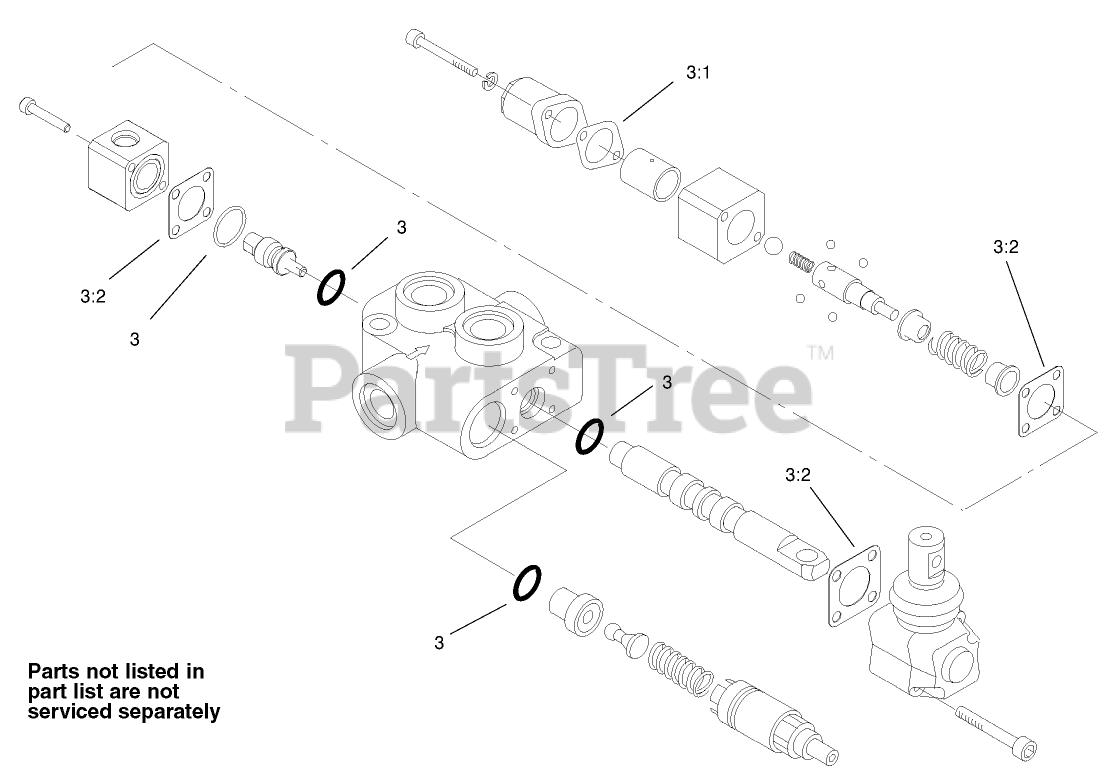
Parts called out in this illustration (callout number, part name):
3	SEAL KIT
3:1	GASKET
3:2	GASKET
